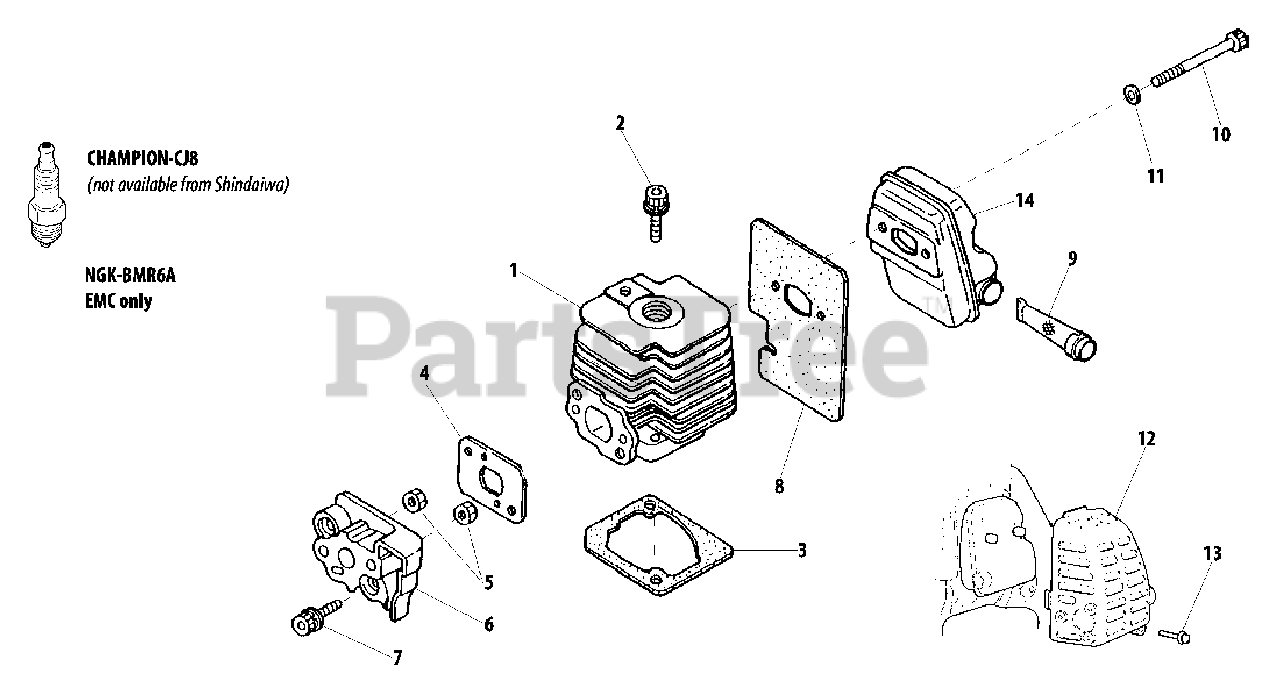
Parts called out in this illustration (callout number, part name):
1	CYLINDER
2	SCREW - 5X25
3	GASKET, CYLINDER
4	GASKET
5	NUT
6	INSULATOR
7	SCREW - 5X25
8	SHIELD, EXHAUST
9	SCREEN, SPARK ARRESTOR
10	SCREW - 5X40
11	WASHER - 5
12	COVER, MUFFLER
13	SCREW
14	MUFFLER
